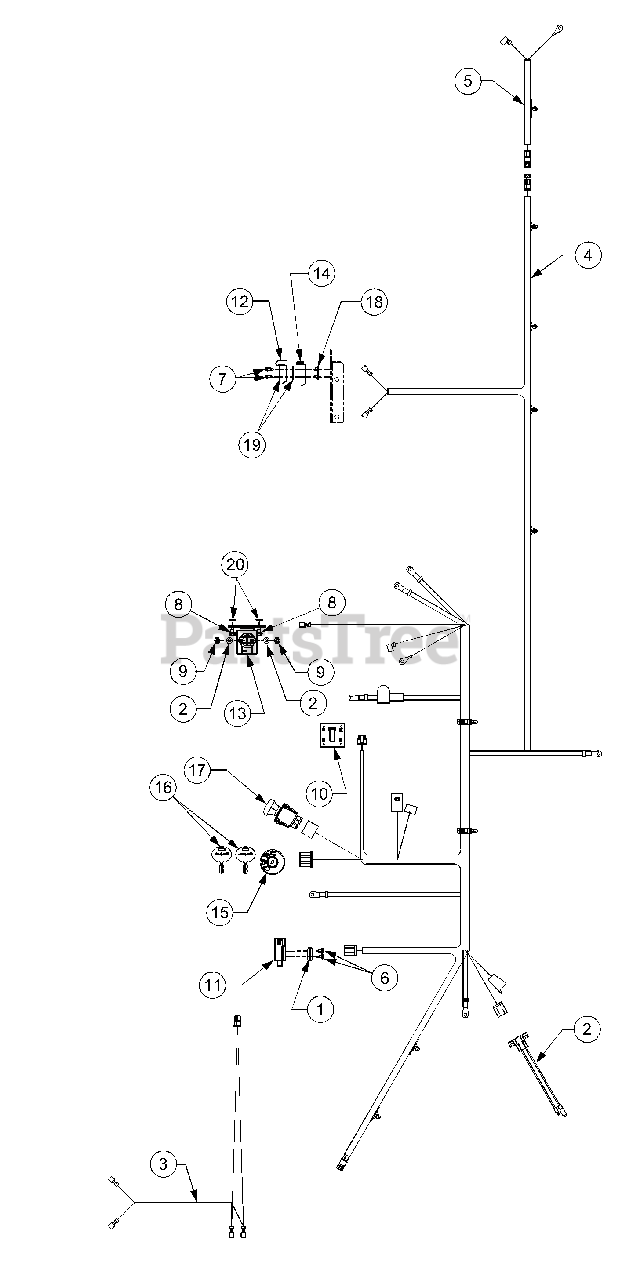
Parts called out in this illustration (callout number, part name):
1	Plate, Switch
2	Washer, Lock, 1/4
3	Harness Assembly, Headlight
4	Harness Assembly
5	Harness Assembly, Safety, Reverse
6	Screw, Hx. Wash. Hd. Tapp, 10-16 x .5
7	Screw, Hx. Wash. Hd. Tapp, 8-18 x .5
8	Screw, Hx. Wash. Hd. Tapp, 1/4-20, 0.75
9	Nut, Hex, 1/4-20, Gr5
10	Indicator/ Meter Hour
11	Switch, Interlock
12	Switch, Outer Seat Spring
13	Solenoid, Starter, 12V
14	Switch, Inner Seat Spring
15	Switch, Key, 4-Position
16	Key, Switch, Plastic
17	Switch, Electric PTO, Yellow Knob
18	Plate, Insulator Boss
19	Plate, Insulator
20	Washer, Lock, Ext 1/4
